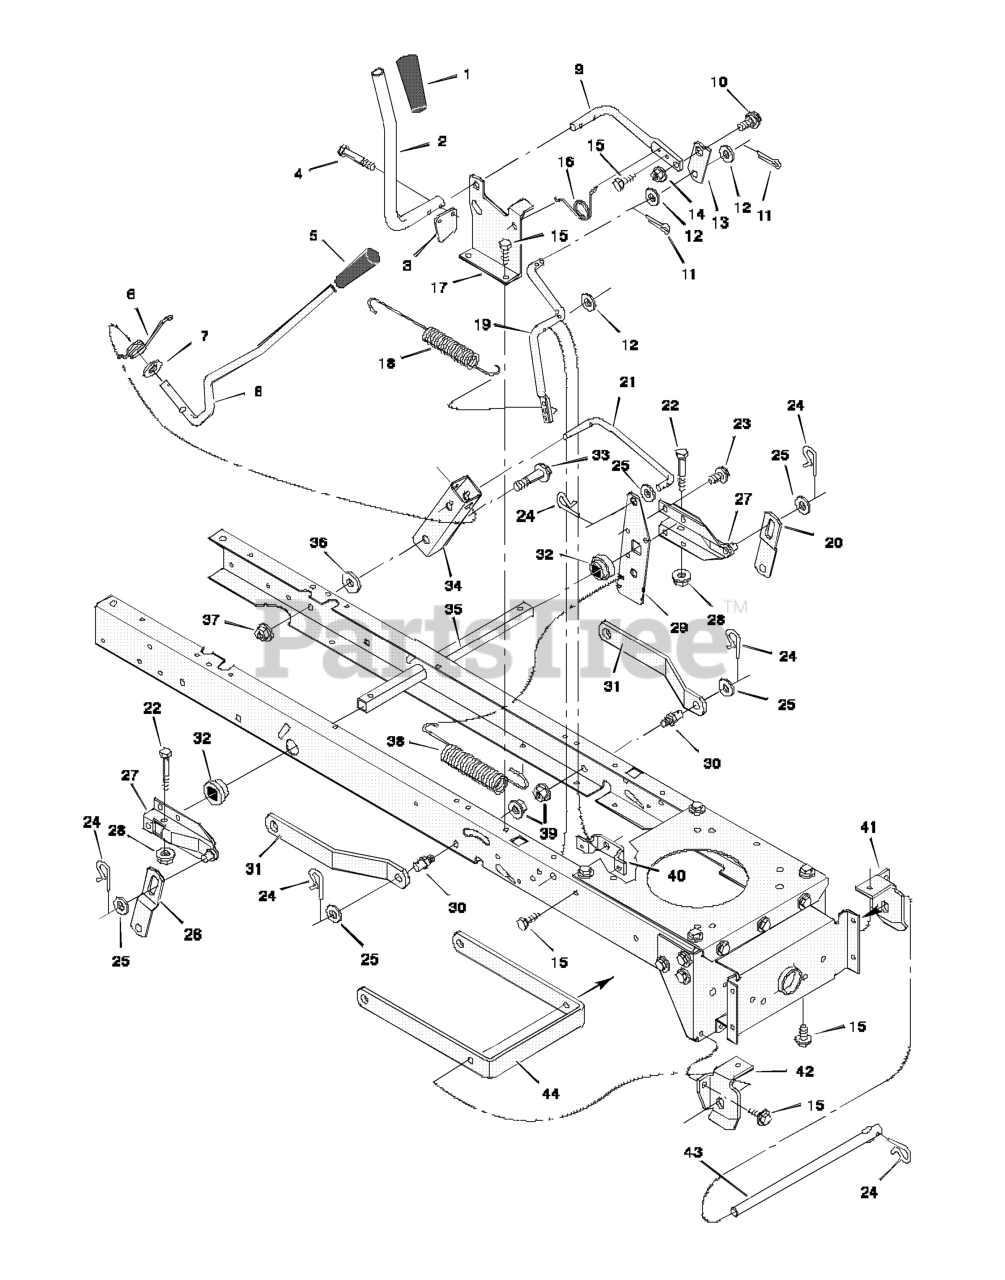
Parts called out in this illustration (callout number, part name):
1	Grip
3	Pad, Switch
4	Screw, Hex
5	Grip
8	Lever, Lift
9	Lever, PTO
10	Bolt, Shoulder
11	Pin, Cotter
12	Washer
13	Link, PTO
14	Nut, Flange
17	Bracket, PTO
19	Crank, PTO
20	Link, Left Lift
21	Link, Lift
24	Pin, Hair
26	Link, Right Lift
27	Lever Assembly, Lift
28	Nut, Flange
29	Plate, Lift Arm
30	Pin
31	Bracket, Rear Suspension
32	Bushing
33	Bolt, Shoulder
34	Bracket, Pivot
35	Tube, Deck Lift
37	Nut, Flange
39	Nut, Flange
40	Bracket, PTO
41	Hanger, Left Deck
42	Hanger, Right Deck
43	Rod, Hanger
44	Bracket, Suspension
